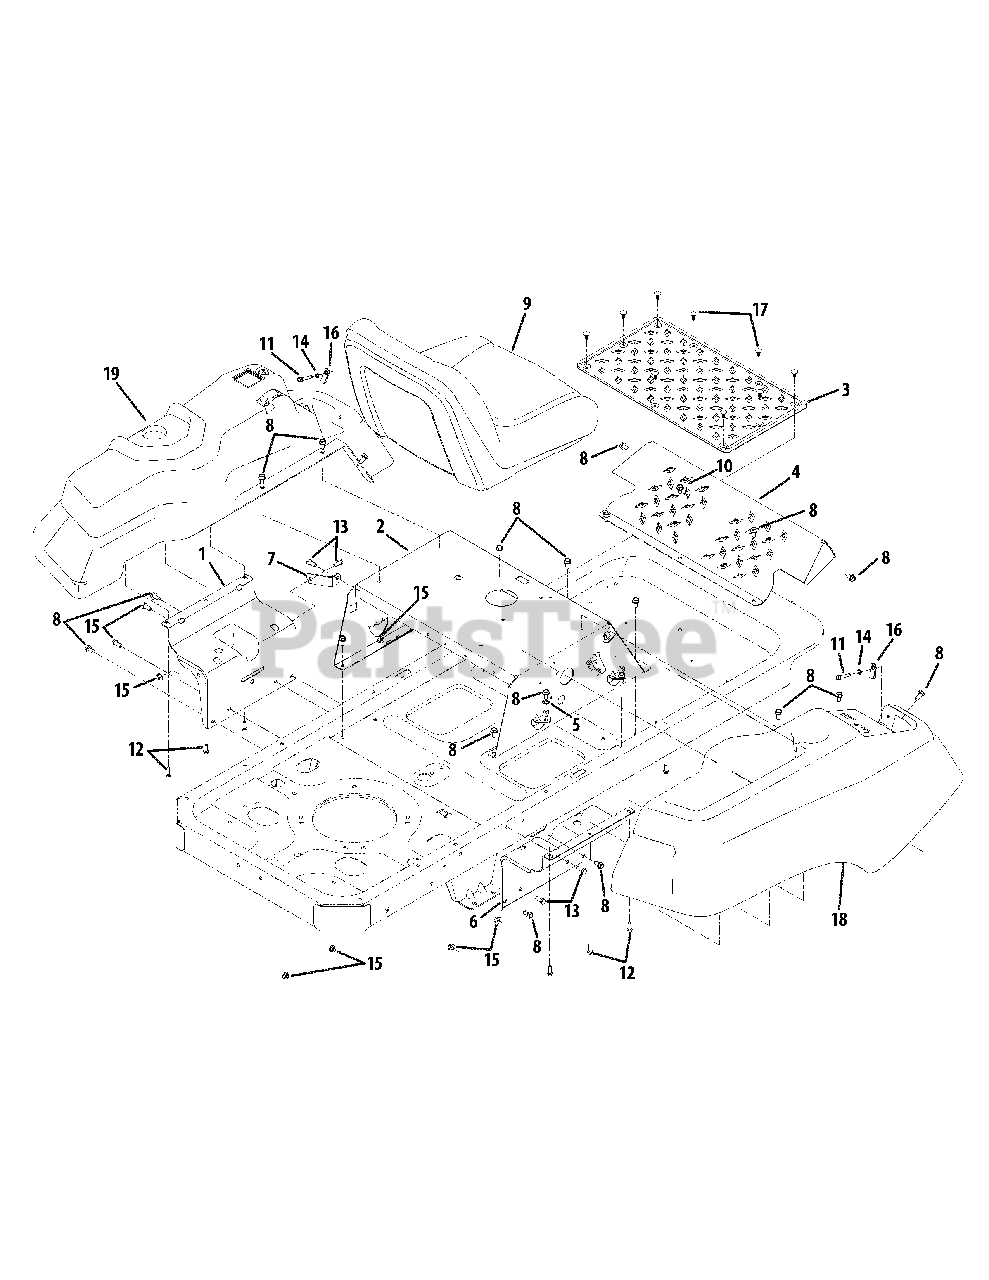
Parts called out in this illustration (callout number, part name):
1	Console Mount Bracket
3	Foot Pad
5	Lock Washer, 3/8
6	Console Mount Bracket
7	Fuel Tank Support Bracket
8	Hex Washer Screw, 5/16-18 x .750
9	High-Back Seat
10	Hex Washer Screw, 5/16-18 x .825
11	Hex Washer Screw, 1/4-20 x 1.500
12	Hex Washer Screw, 1/4-15 x .750
13	Hex Screw, 5/16-18 x .75
14	Jam Nut, 1/4-20
15	Flange Lock Nut, 5/16-18
16	U-Type Nut, 1/4-20
17	Ratchet Clip, .250
18	RH Console
19	LH Console
